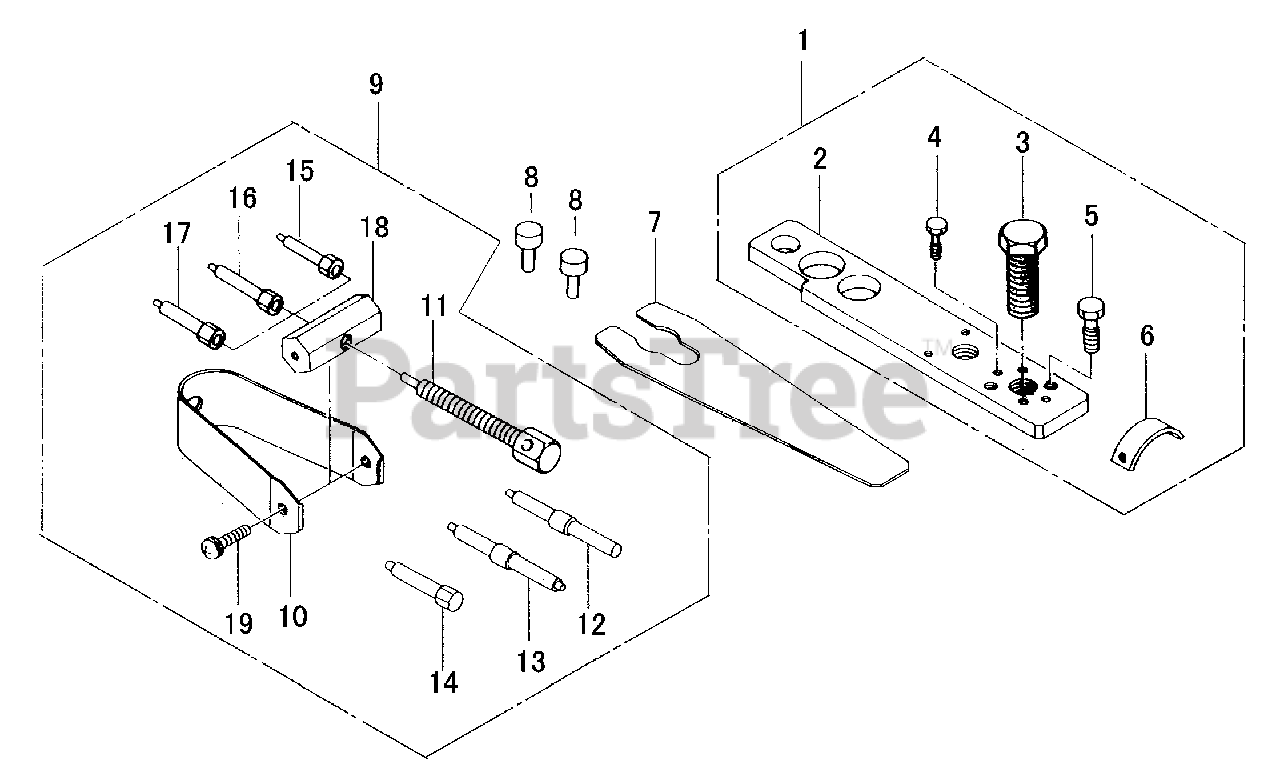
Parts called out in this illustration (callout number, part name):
2	LEVER
3	CENTER BOLT
4	BOLT
5	BOLT
6	AIR GAP GAUGE
7	ROTOR SPANNER
8	STOPPER
9	PULLER ASSY
11	BOLT
12	GUIDE PIN
13	GUIDE PIN
14	GUIDE PIN
15	PIN - ADAPTOR
16	PIN - ADAPTOR
17	PIN - ADAPTOR
18	BOSS
19	SCREW - 6X12
